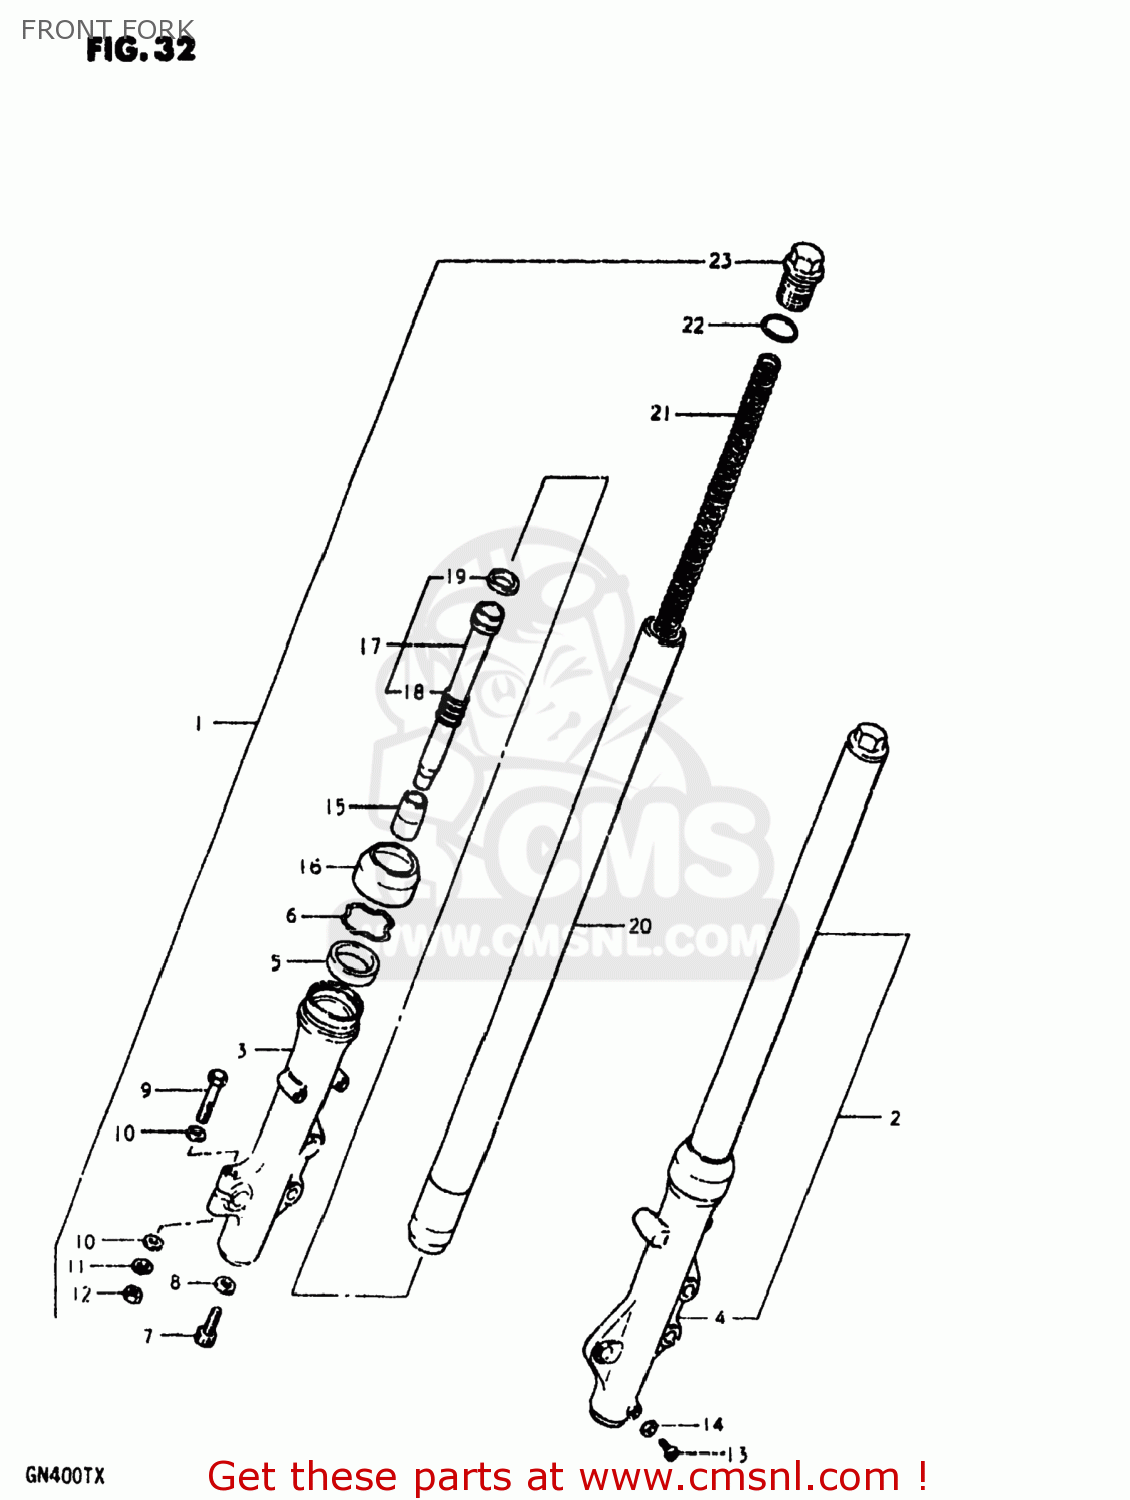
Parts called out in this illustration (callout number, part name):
1	DAMPER ASSEMBLY,RIGHT
2	DAMPER ASSEMBLY,LEFT
3	TUBE,OUTER,RIGHT
4	TUBE,OUTER,LEFT
5	OIL SEAL,FRONT FORK
6	7
7	BOLT,FORK CYLINDER(10X25)
8	GASKET (NAS)
9	BOLT 8X50
10	WASHER
11	WASHER,LOCK,8.
12	NUT
13	SCREW
14	GASKET,DRAIN,PLUG (NAS)
15	PIECE,OIL LOCK
16	SEAL,DUST
17	CYLINDER,FRONT FORK
18	SPRING,FORK REBOUND
19	RING,FRONT FORK PISTON
20	TUBE,FORK,INNER
21	SPRING,FRONT FORK
22	O-RING,FORK FITTING BOLT
23	BOLT,FORK
